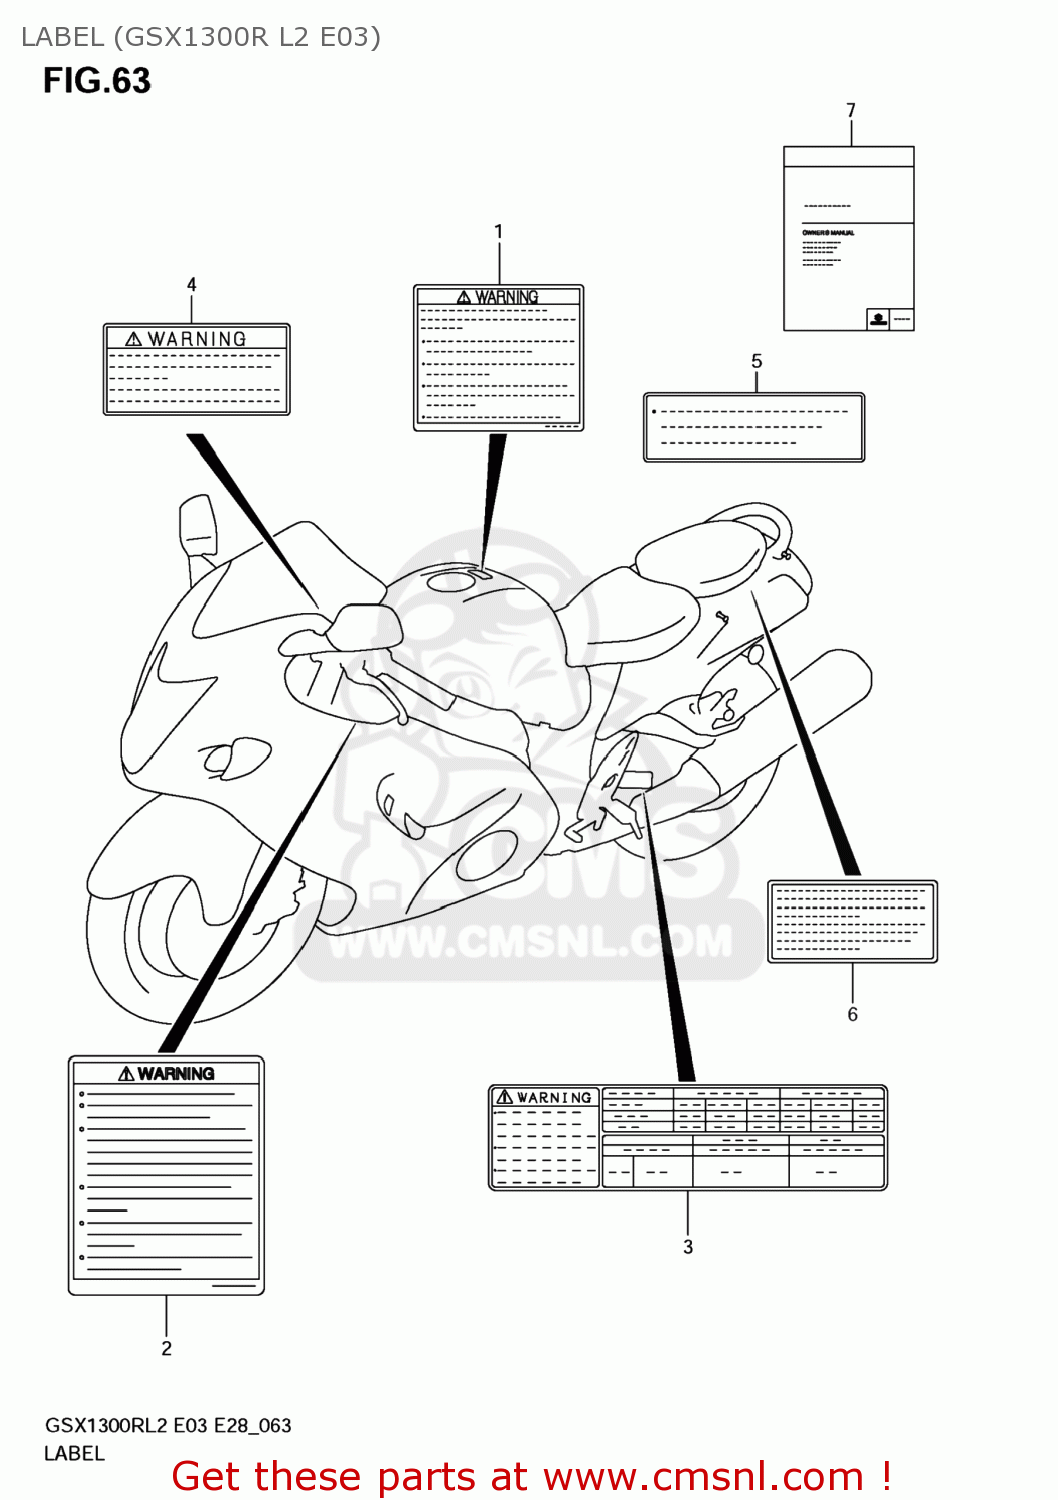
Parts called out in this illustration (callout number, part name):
1	LABEL,GENERAL WARNING
2	LABEL,SCREEN
3	LABEL,TIRE INFORMATION
4	LABEL,WARNING STEERING
5	LABEL,FUEL INFORMATION
6	LABEL,MANUAL NOTICE
7	MANUAL,OWNER'S
